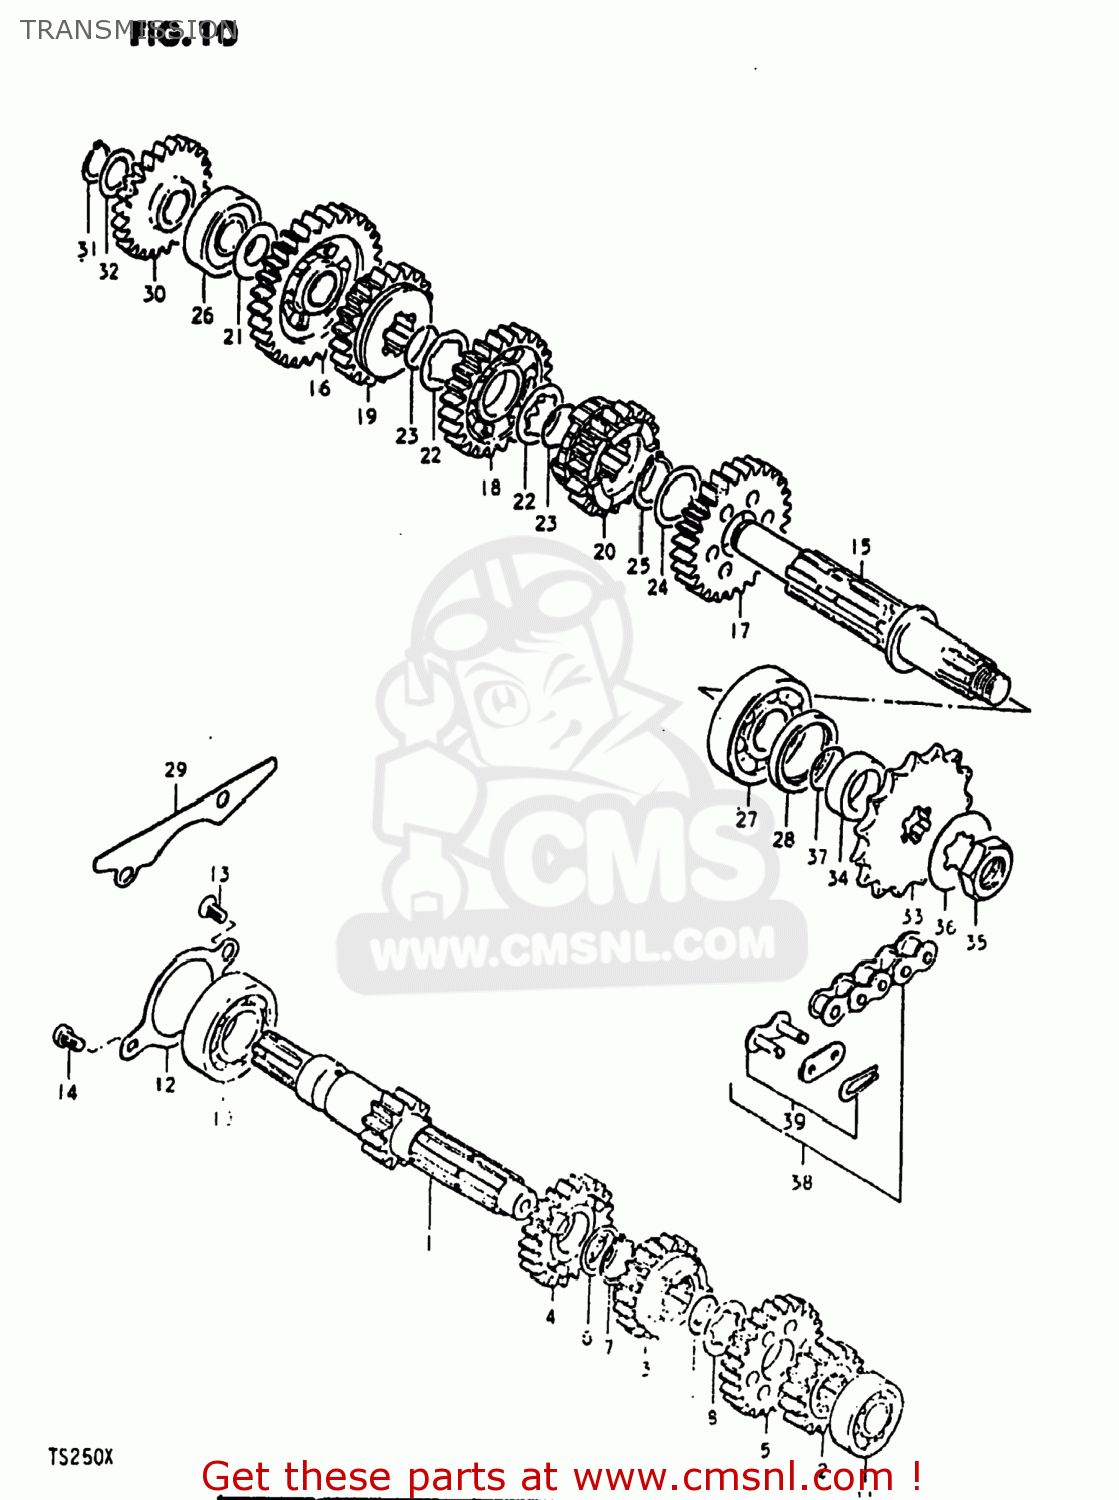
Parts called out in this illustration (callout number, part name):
1	SHAFT,COUNTER
2	GEAR,SECOND DRIVE
3	GEAR,THIRD DRIVE
4	GEAR,FOURTH DRIVE
5	GEAR,FIFTH DRIVE
6	SHIM
7	CIRCLIP
8	WASHER,LOCK
9	CIRCLIP
10	BEARING
11	BEARING
12	PLATE,COUNTERSHAFT BEARING
13	SCREW
14	SCREW 6X12
15	SHAFT,DRIVE
16	GEAR,FIRST DRIVEN
17	GEAR,SECOND DRIVEN
18	GEAR,THIRD DRIVEN
19	GEAR,FOURTH DRIVEN
20	GEAR,5TH DRIVEN
21	WASHER,THRUST
22	WASHER,LOCK
23	RING,SNAP
24	WASHER
25	CIRCLIP
26	BEARING
27	BEARING
28	SEAL,OIL(32X42X6)
29	PLATE,OIL RESERVOIR
30	GEAR,KICK STARTER IDLE
31	CIRCLIP
32	WASHER
33	SPROCKET,ENGINE
34	SPACER(22X32X11.5)
35	NUT
36	WASHER,LOCK
37	O RING(D:1.7,ID:22)
38	CHAIN,DRIVE #525TR-10
39	JOINT ASSEMBLY,CHAIN
